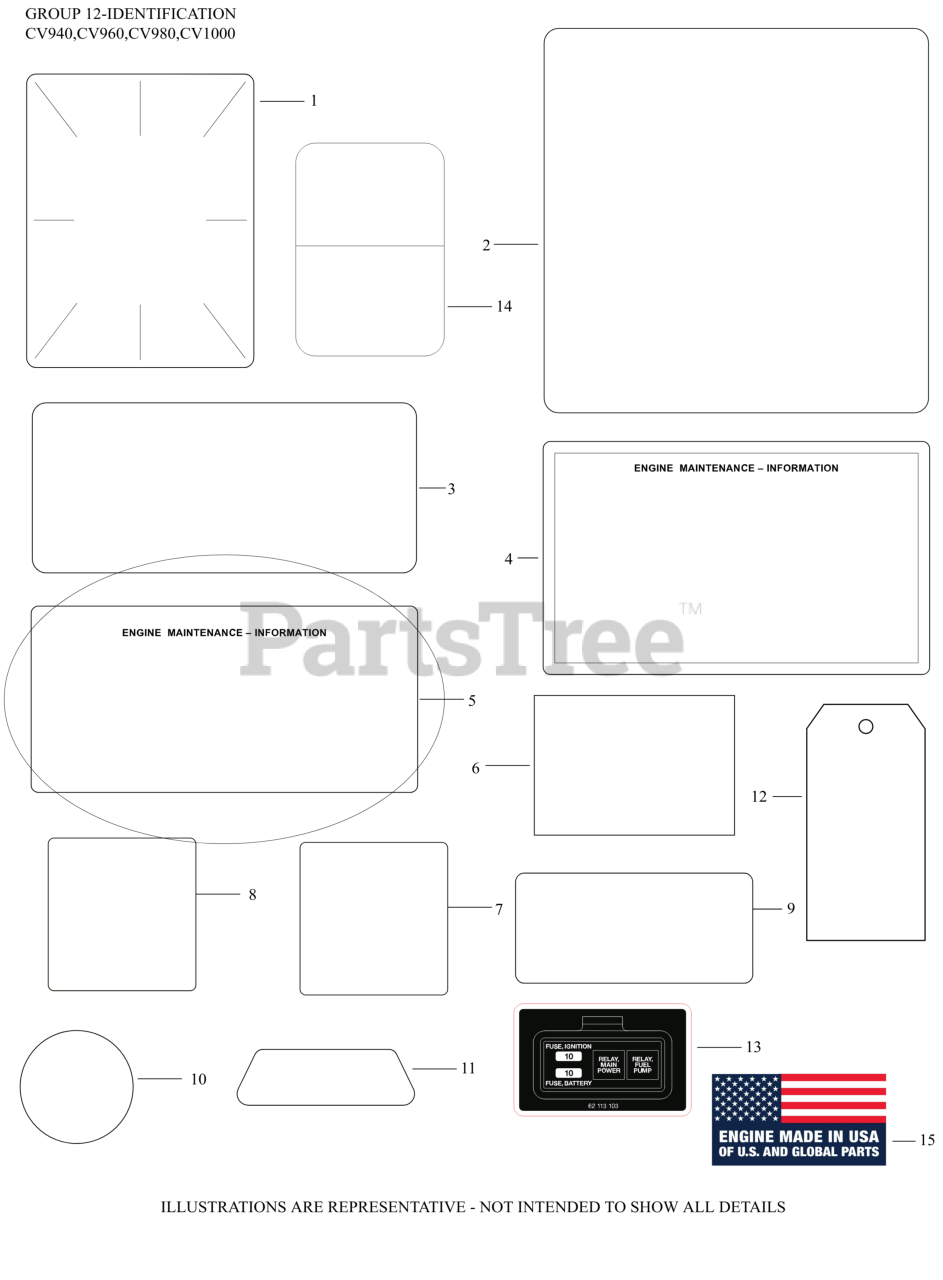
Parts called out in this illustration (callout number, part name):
1	LABEL, CLEAR LAMINATION
2	DECAL, 35 HP/999cc/CV-CH980
10	LABEL, GRASS SCREEN
NI	DECAL, USA
